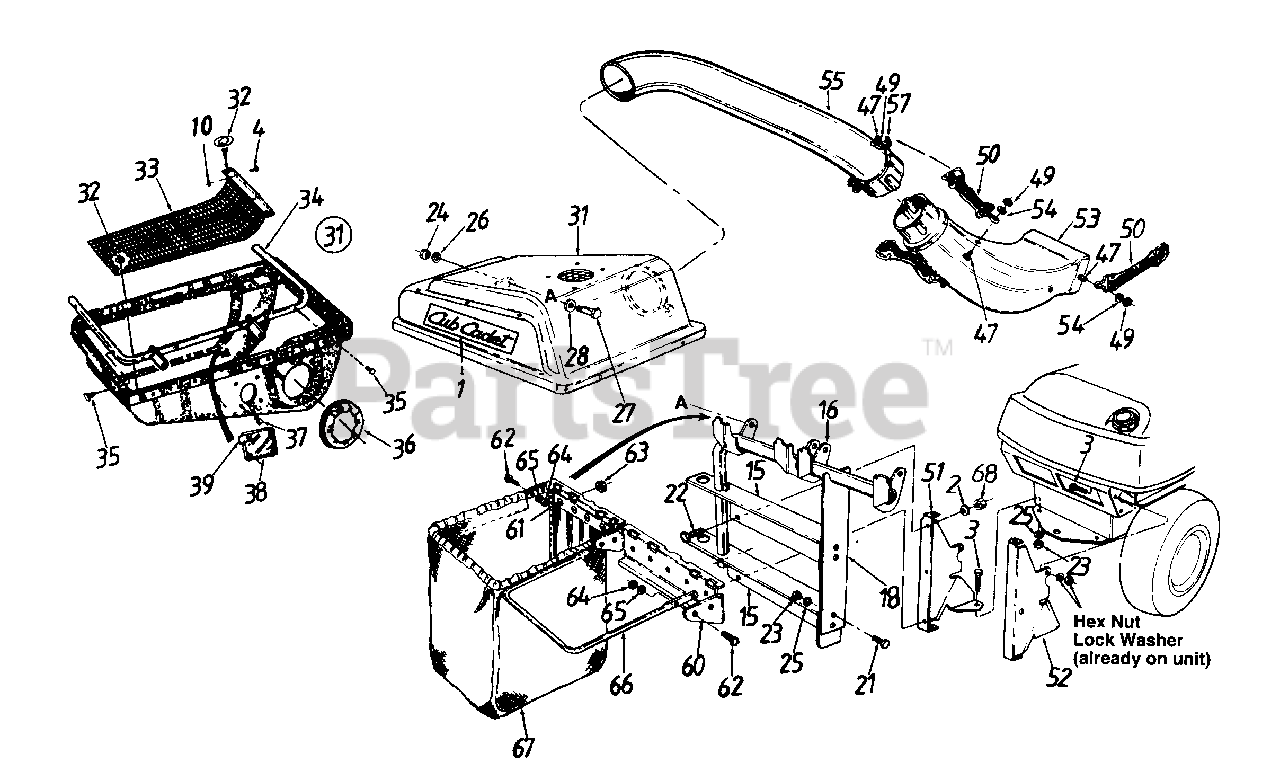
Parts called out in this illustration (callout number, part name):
1	Cub Cadet Name Plate
2	Fl-Wash. 1/4" I.D.
3	Hex Bolt 5/16-18 x 1.0" Lg.
4	Pop Rivet .188 Dia.
10	Flat Wash. 1/4" I.D.
21	Hex Bolt 5/16-18 x .75"
22	Hex Bolt 1/4-20 x .62" Lg.- Grade 5
23	Hex Nut 5/16-18 Thd.
24	Hex Nut 3/8-16 Thd.
25	L-Wash. 5/16" I.D.
26	L-Wash. 3/8" I.D.
27	Shld. Bolt 3/8-16 x .50" Dia.
28	Bell-Wash. .505" I.D. x 1.0" O.D.
31	Grass Catcher Cover Ass'y
32	Twist Fastener
35	Hex AB-Tap Scr. 1/4 x .62"
37	Truss B-Tap Scr. #10 x .5" Lg.
38	Plastic Plate
39	Speed Nut
47	Hex Bolt 1/4-20 x .625"
49	Hex Ins. L-Nut 1/4-20 Thd.
50	Retainer Strap Ass'y.
51	Catcher Support Brkt.-L.H.
52	Catcher Support Brkt.-R.H.
53	Discharge Chute
54	L-Wash. .27" I.D.
55	Catcher Tube
57	Retainer Hook Brkt.
61	Truss Mach. Scr. #10-24 x .5"
62	Hex Bolt 1/4-28 x .88"
63	Hex Sems Nut #10-24 Thd.
64	Hex Nut 1/4-28 Thd.
65	L-Wash. 1/4" I.D.
67	Grass Catcher Bag
68	Hex L-Nut 1/4-20 Thd.
